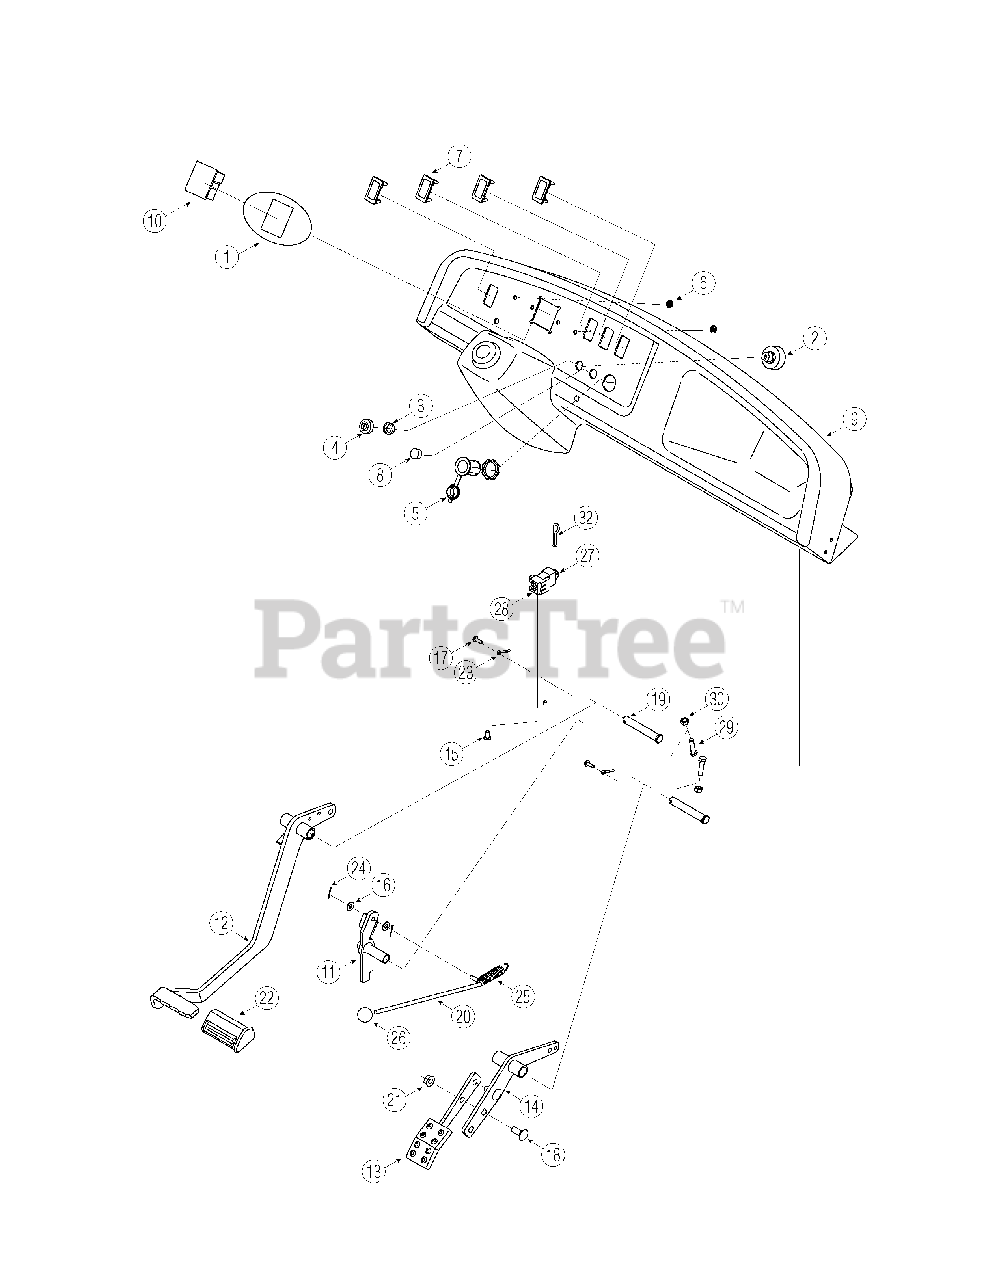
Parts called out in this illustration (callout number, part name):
1	Instrument Dash Cover
2	Key Switch
3	Nut, Ignition Switch, 5/8-32
4	Cap, Ignition Switch
5	Power Receptacle, 12V
6	Nut, Retainer, 1/8
7	Switch Plug Panel
8	Plug, Horn Switch
9	Dash Panel
10	Hour Indicator Meter
11	Lever, Parking Brake
14	Pedal Arm Assembly, Throttle
15	Screw, Hi-Lo, 1/4-20 x .5
16	Washer, Flat .25 x .630 x .0515
17	Screw, Self-tapping, #10-32 x.625
18	Bolt, Carriage, 3/8-16 x 1.0
19	Pin, Clevis.50 x 3.25
20	Rod, Brake Lock
21	Nut, Flange Lock, 3/8-16
22	Pad, Brake Pedal
23	Pin, Cotter, 5/32 x 1.00
24	Pin, Cotter, 1/16
25	Spring, Extension, .637 x 2.972
26	Knob, Ball
27	Cover, Protective
28	Snap Mount Switch, Interlock
29	Hex Screw, 5/16-18 x 1.25
30	Hex Nut, 5/16-18
32	Cotter Pin
